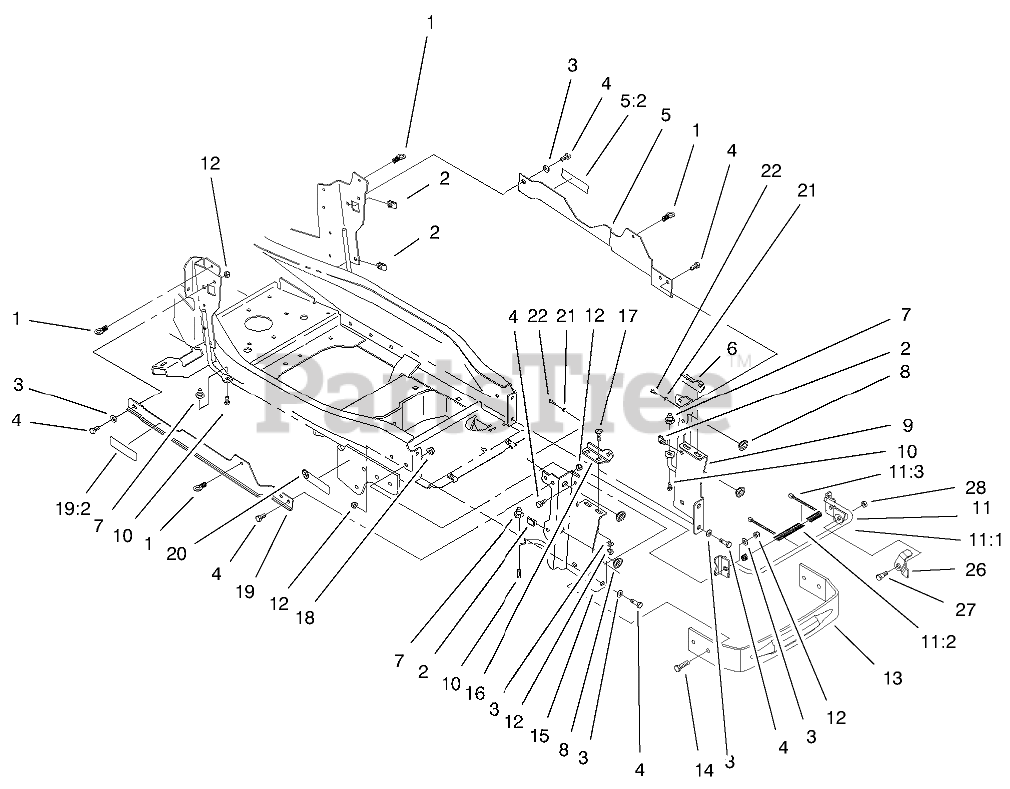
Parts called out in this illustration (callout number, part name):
1	LATCH ASM
3	WASHER-PLAIN
4	SCREW-HH
5	ASM-Support w/Decal (Only On: 73471, 73542)
5	ASM-Support w/Decal (Only On: 73570)
5:2	Decal-Warning (Only On: 73570)
5:2	Decal-Warning (Only On: 73471, 73542)
6	BRACKET-HINGE, LOWER LH
7	MOUNT-SIDEPANEL
8	GROMMET
9	SUPPORT-HOOD, LH
10	SCREW-PLASTITE
11	SUPPORT-HOOD
11:1	Hood Support Brace W.a.
11:2	COVER-BRACE
11:3	TIE-CABLE
12	NUT-LOCK, NI
13	BUMPER-FRAME
14	SCREW-HH
15	SUPPORT-HOOD, RH
16	BRACKET-HINGE, LOWER RH
17	SCREW-CARR
18	NUT-LOCK, NI
19	ASM Support/Decal (Only On: 73570)
19	ASM-Support/Decal (Only On: 73471, 73542)
19:2	Decal-Warning (Only On: 73570)
19:2	Decal-Warning (Only On: 73471, 73542)
20	DECAL-ATTACH A-MATIC
21	Washer-Flat (Only On: 73570)
22	Screw-Selftap (Only On: 73570)
26	LEVER-PROP, HOOD
27	BOLT-SHOULDER
28	NUT-LOCK, NI
